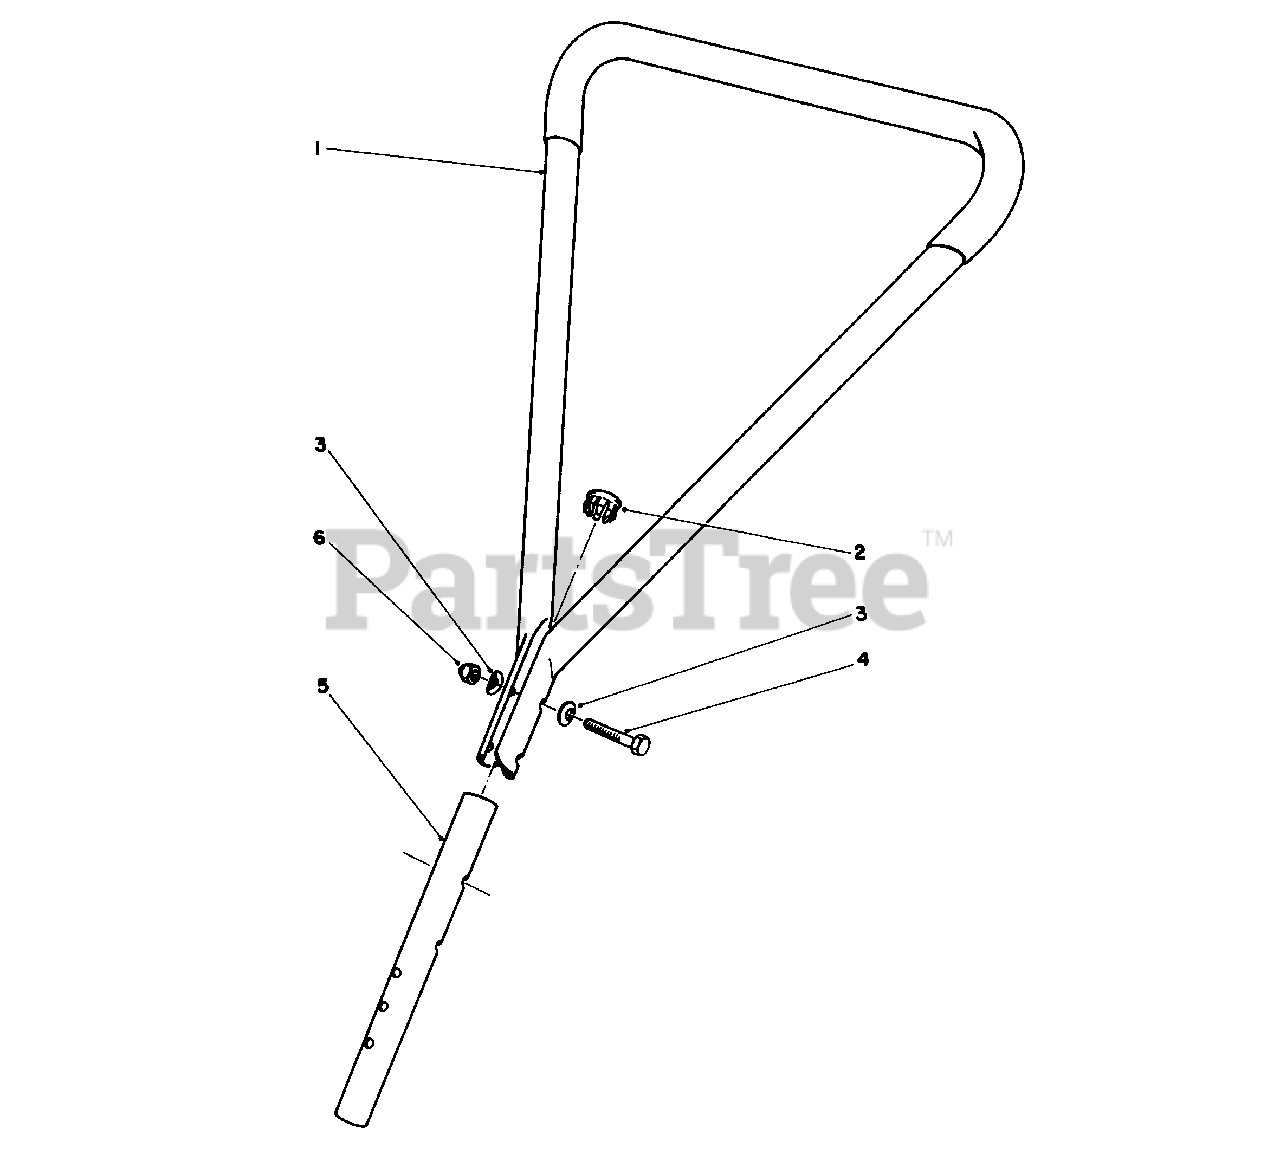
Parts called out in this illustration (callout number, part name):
1	Tube-Handle
2	Closure-Tube
3	Washer-Curved
4	Screw-Hex. Hd.
5	Tube-End
6	Nut-Cap Lock
